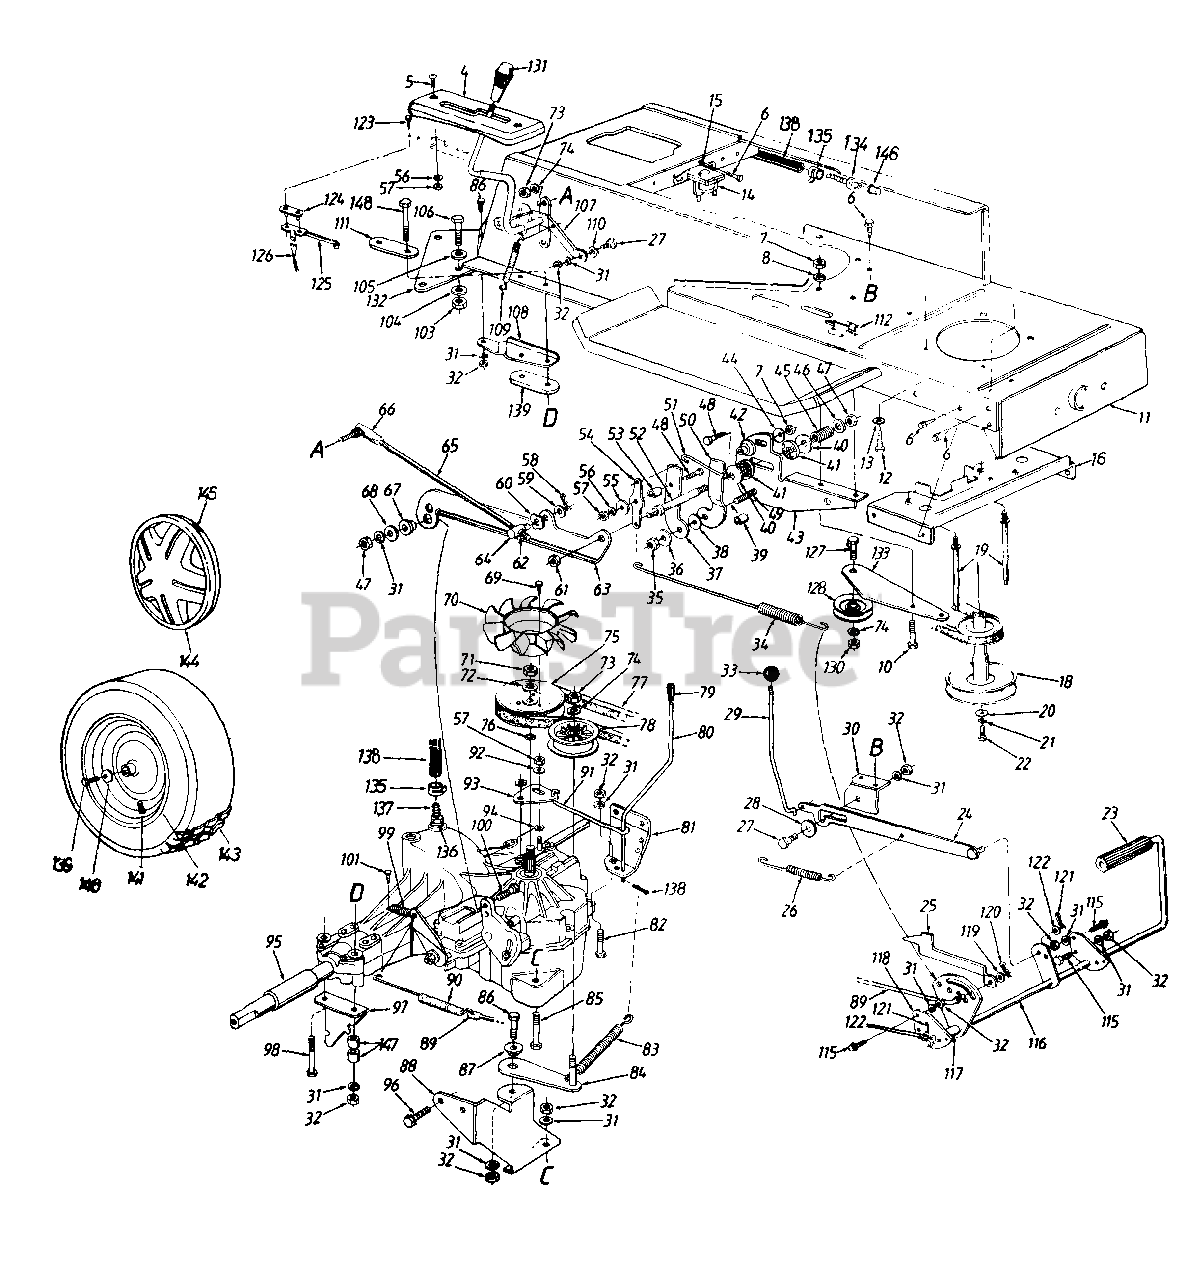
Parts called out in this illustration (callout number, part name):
4	Index Bracket
5	Pan Hd. Mach. Scr. 1/4-20 x .75" Lg.
6	Hex Wash. Hd. TT-Tap Scr. 1/4-20 x .5" Lg.
7	Hex Nut 1/4-28 Thd.
8	L-Wash. 1/4" I.D.
10	Hex Bolt 1/4-28 x .75" Lg.
11	Lower Frame Ass'y.
12	Hex Tap Scr. 3/8-16 x 1.5" Lg.
13	Fl-Wash. .406" I.D. x 1.25"
14	Solenoid
15	Ext. L-Wash. 1/4" I.D.
16	Belt Guard Brkt. Ass'y.
18	Engine Pulley
19	Belt Guard Stud 3.6" Lg.
20	Fl-Wash. 7/16" I.D. x 1.25" O.D.
21	L-Wash. 7/16" I.D.
22	Mex Bolt 7/16-20 x 1.5" Lg.
23	Foot Pad
26	Foot Pedal Return Spring
27	Shld. Bolt .437" Dia. x .268"
28	Fl-Wash. 7/16" I.D. x 1-3/8" O.D.
29	Lock-up Rod
30	Bracket
31	L-Wash. 5/16" I.D.
32	Hex Nut 5/16-18 Thd.
33	Ball Knob
34	Neutral Return Spring
35	Hex Nut 5/16-24 Thd.
36	Fl-Wash. .344" I.D. x 1" O.D.
37	Scissor-Flat
38	Fl-Wash..33" I.D. x 1.25" O.D.
39	Spacer
40	Bell-Wash. .4" I.D. x 1.13" O.D.
41	Friction Washer
42	Centering Gauge Spacer
43	Neutral Return Mtg. Brkt.
44	Bell-Wash. .265" I.D. x .75" O.D.
45	Comp. Spring 1.19" Lg.
46	Fl-Wash. .312" I.D. x .75" O.D.
47	Hex Nut 5/16-24 Thd.
48	Hex Bolt 1/4-28 x 1" Lg. (Gr. 5)
49	Rib Neck Bolt 5/16-24 x .84" Lg.
50	Scissor-Offset
51	Neutral Return Rod
52	Friction Disc Stud
53	Shld. Spacer
54	Neutral Return Lever
55	Fl-Wash. .265" I.D. x 1" O.D.
56	L-Wash. 1/4" I.D.
57	Hex Nut 1/4-20 Thd.
58	Hairpin Clip
59	Fl-Wash. .375" I.D. x .87" O.D.
60	Spring Wash. .39" I.D.
61	Hex L-Nut 3/8-24 Thd.
62	Hex Jam Nut 3/8-24 Thd.
63	Neutral Return Brkt.
64	Ferrule 3/8-24 Thd.
65	Control Rod
66	Ball Joint 3/8-24 Thd.
67	Shld. Spacer .5" Dia. x .27" Lg.
68	Fl-Wash .349" I.D. x .879" O.D.
69	Hex Wash. Hd. Tap Scr. #12 x 3/8" Lg.
70	Fan
71	Hex Nut 1/2-20 Thd.
72	L-Wash. 1/2" I.D.
73	Hex Nut 3/8-24 Thd.
74	L-Wash. 3/8" I.D.
75	Transmission Pulley
76	Wire Ring
77	"V"-Belt
78	Fl-Idler Pulley 2.75" O.D.
79	Rod End Grip
80	Bypass Control Lever
83	Ext. Spring 6.12
86	Hex Bolt 5/16-18 x .75" Lg.
87	Shld. Spacer .5" Dia. x .27" Lg.
90	Ext. Spring
91	Bypass Actuator Rod
92	Fl-Wash. .281" I.D. x .5" O.D.
93	Bypass Adjustment Brkt.
94	External L-Wash. 1/4" I.D.
95	Sleeve .758" I.D. x 1" O.D.
96	Hex . Wash. TT-Tap Scr. 5/16-18 x .62" Lg.
99	Tension Spring
100	Hex Bolt 5/16-24 x 1" Lg. (Special)
101	Hex Wash. Hd. AB-Tap Scr. #10 x .5" Lg.
103	Hex Nut 7/16-14 Thd. (Gr 5)
104	Fl-Wash. .469" I.D. x .875" O.D.
105	Bell-Wash. .46" I.D. x 1.13" O.D.
106	Hex Bolt 7/16-14 x 1" Lg.
107	Speed Control Lever Ass'y.
110	Spr-Wash. .445" I.D. x 75" O.D.
112	Safety Switch (Clutch)
115	Hex Wash. TT-Tap Scr. 5/16-18 x .75" Lg.
120	Cotter Pin 3/32" Dia.
121	Cotter Pin 1/8" Dia.
122	Fl-Wash. .64" I.D. x .94" O.D.
123	Hex Wash. Hd. AB-Tap Scr. #8 x .5" Lg.
124	Insulator Nut Plate
125	Reverse Safety Switch
126	Extension Wire
127	Hex Bolt 3/8-16 x 1.5" Lg.
128	Idler Pulley
130	Hex Nut 3/8-16 Thd.
131	Shift Knob
132	Hitch Plate Extension
135	Clamp
136	"O"-Ring
137	Hose Fltting
138	Fuel Line 18" Lg.
139	Hex Bolt 5/16-24 x .75" Lg.
140	Bell-Wash. .345" I.D. x .88" O.D.
141	Air Valve
142	Rim Only
143	Wheel Ass'y. Comp.
144	Hub Cap (Gray)
145	Spring Clip
146	Vent Cap
147	Spacer .315" I.D. x .75" O.D.
148	Hex Bolt 5/16-18 x 4.5" Lg. (Used w/46" Deck)
